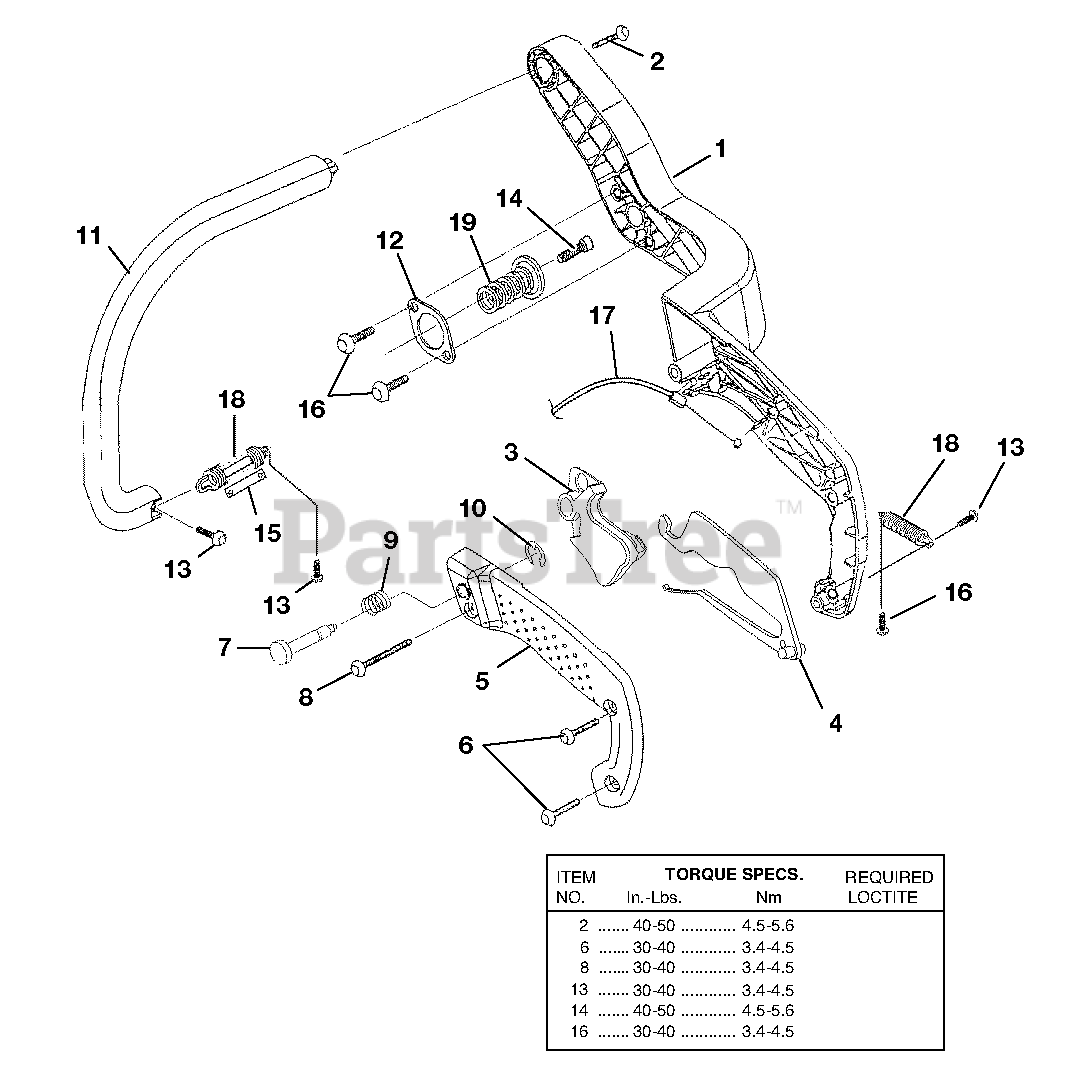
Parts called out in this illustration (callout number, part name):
1	Rear Handle
2	Screw (12-14x1-1/2in.)
3	Throttle Trigger
4	Throttle Lock Out
5	Handle Cover
6	Screw (10-14x3/4in.)
7	Throttle Pin Lock
8	Screw (10-14x1-3/8 in.)
10	E-Ring
11	Front Handle
12	Isolator Plate
13	Screw (10-14x5/8in.)
14	Screw (10-24x5/8in.)
15	Limiter, Isolator
16	Screw (10-14x1/2in.)
17	Throttle Cable
18	Extension Spring
19	Upper Isolation Spring
